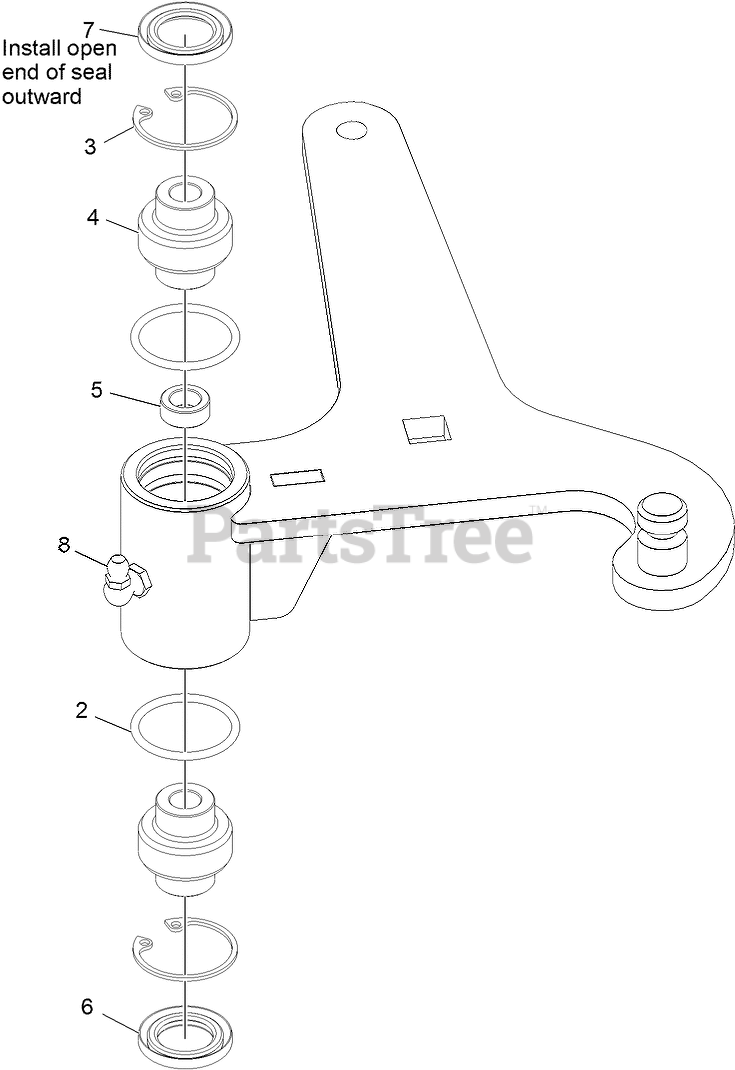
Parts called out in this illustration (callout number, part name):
3	RING-SNAP
4	BEARING-SPHERICAL
6	SEAL-LIP, DOUBLE
7	SEAL-LIP, SINGLE
8	FITTING-GREASE, 90 DEG
